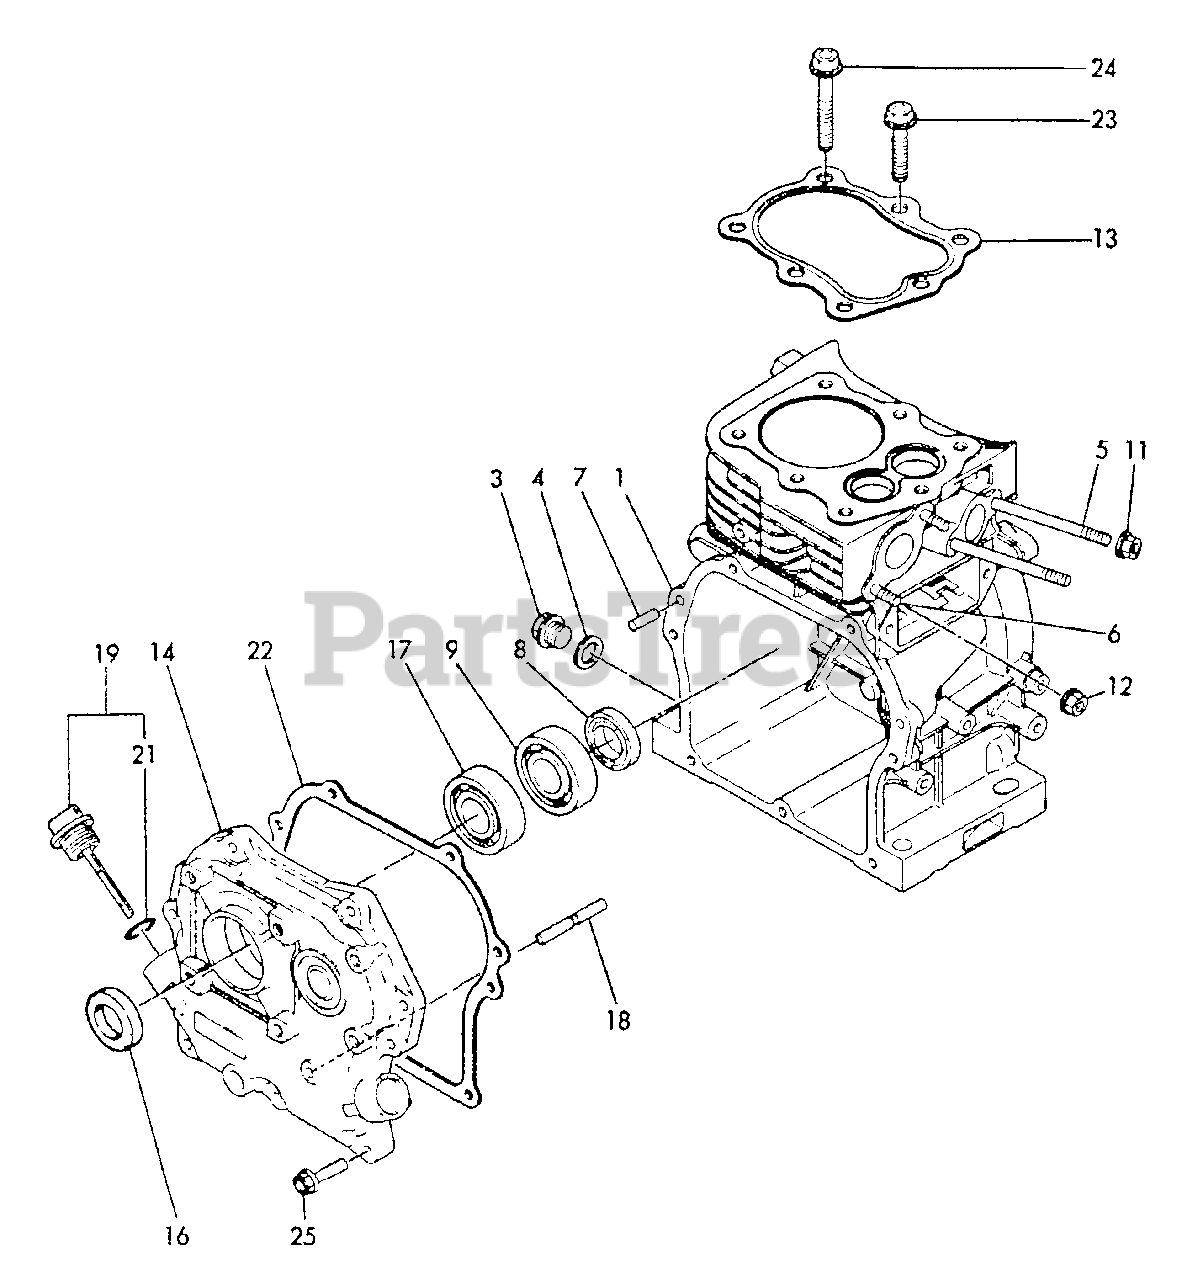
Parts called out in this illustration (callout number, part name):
1	CYLINDER BLOCK SET
3	PLUG, DRAIN
4	GASKET
5	BOLT - 6X70
6	BOLT - 6X16
7	PIN - 6X16
8	SEAL, OIL
9	BEARING, BALL - 6204C3
11	NUT - 6 -- FLANGE
12	NUT - 6 -- FLANGE
13	GASKET, CYLINDER
14	SIDE COVER ASSY
16	SEAL, OIL
17	BEARING, BALL - 6204C3
18	SHAFT, GOVERNOR
19	CAP ASSY
21	O-RING - 18
22	GASKET
23	BOLT - 8X39
24	BOLT - 8X60
25	BOLT - 6X25
